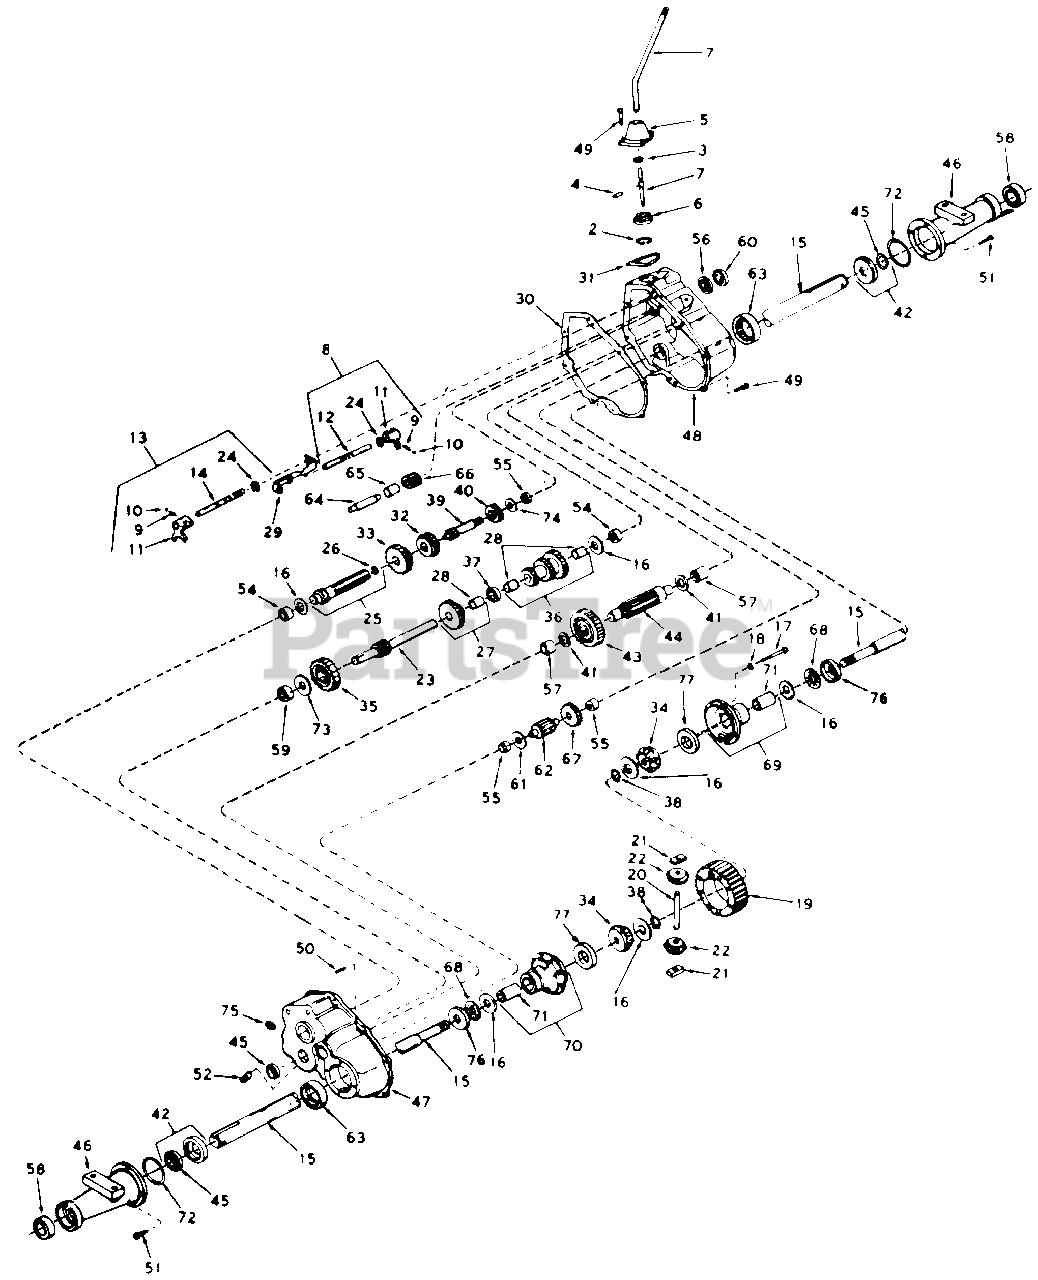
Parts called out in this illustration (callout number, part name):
2	Ring, Snap
3	Ring, Quad
4	Pin, Roll
5	Housing, Shift Lever
6	Keeper, Shift Lever
7	Lever, Shift
8	Rod Ass'y., Shift
9	Spring
10	Ball, Steel
11	Fork, Shifter
12	Rod. Shifter
13	Rod Ass'y., Shift
14	Rod, Shifter
15	Axle (18-11/32" Long)
16	Washer, Thrust
17	Scr., Hex Hd., 1/4-20 x 2l/2
18	Lock Washer, 1/4"
19	Gear, Ring
20	Pin, Drive
21	Block, Drive
22	Pinion, Bevel
23	Shaft and Gear, Brake
24	Ring, Snap
25	Shaft and Bearing Ass'y., Pinion
26	Bearing, Needle
27	Gear Cluster Ass'y.
28	Bushing
29	Stop, Shifter
30	Gasket, Case and Cover
31	Gasket, Shifter Lever Housing
32	Gear, Shifting
33	Gear, Shifting
34	Gear, Bevel
35	Gear, Idler
36	Gear Cluster Ass'y.
37	Spacer
38	Ring, Snap
39	Shaft, Input
40	Spur Gear, Input Shaft
41	Washer, Thrust
42	Seal and Retainer Ass'y., Oil
43	Gear, Output
44	Pinion, Output
45	Seal, Oil
46	Housing, Axle
47	Cover Ass'y., Transaxle
48	Case Ass'y., Transaxle
49	Screw, Socket Hd., 1/4-20 x 314
50	Pin, Dowel
51	Screw, Hex Hd. Sems, 5/16-18 x 1
52	Plug, Magnetic Drain
54	Bearing, Needle
55	Bearing, Needle
56	Bearing, Ball
57	Bearing, Needle
58	Bearing, Ball
59	Bearing, Needle
60	Seal, Oil
61	Washer
62	Shaft and Pinion
63	Bearing, Needle
64	Shaft, Reverse Idler
65	Spacer, Reverse Idler
66	Idler, Reverse
67	Spur Gear (22 Teeth)
68	Bearing, Thrust
69	Carrier Ass'y., Differential
70	Carrier Ass'y, Differential
71	Bushing
72	O Ring
73	Washer, Thrust
74	Washer, Thrust
75	Plug, Pipe
76	Race, Thrust
77	Washer
